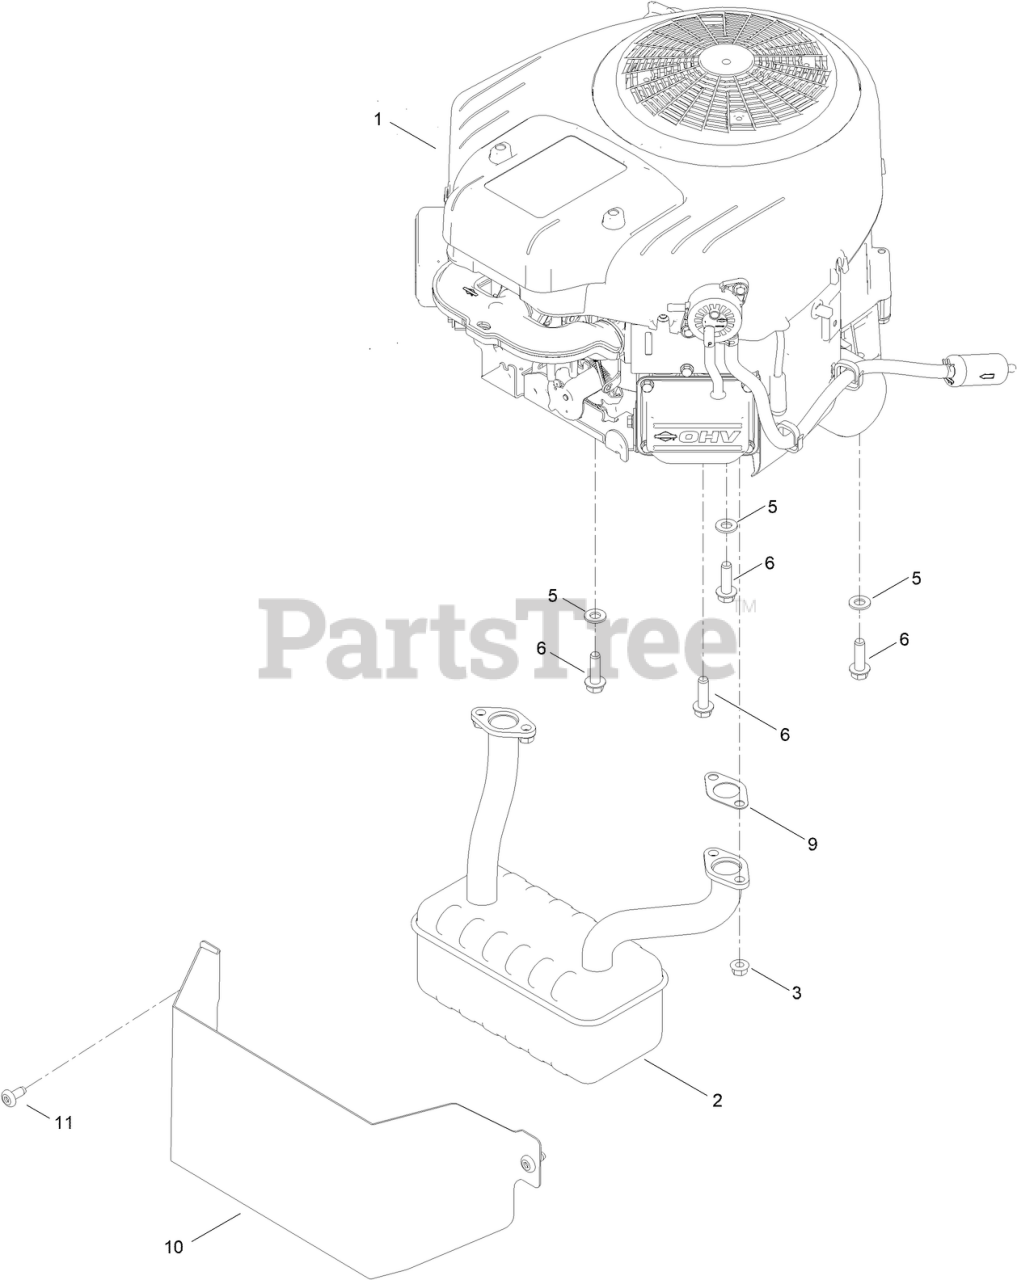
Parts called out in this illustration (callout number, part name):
1	ENGINE - BS EXI
2	MUFFLER
3	NUT-HF
5	WASHER-FLAT
6	SCREW-HWH, THD ROLL
9	GASKET-EXHAUST, BRIGGS TWIN
10	HEAT SHIELD - MUFFLER
